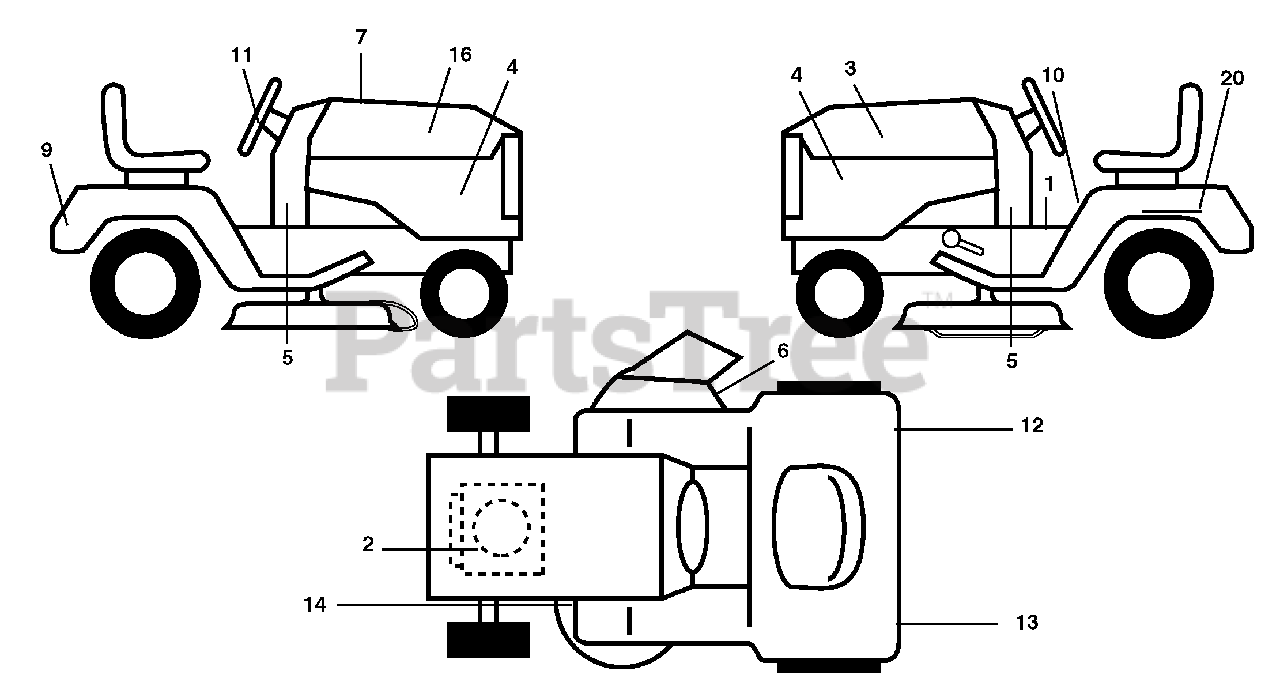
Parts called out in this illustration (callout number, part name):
2	Decalengine
3	Decal Hood LH
4	Decal Side Panel Logo
5	Decal Dash
6	Decal Warning, Keep Hand Away
7	Decal Replacement Parts
9	Decal Fender Logo
10	Decal Fender Danger E/F
11	Decal Ins Strg Whl
12	Decal Fend Reflector Rh
13	Decal Fend Reflector Lh
14	Decal V-Belt Schematic
16	Decal Hood Rh
20	Decal Bat Dan/Psn
20	Pad Footrest LH
20	Pad Footrest RH
20	Decal Handle Lft Height Adjust
20	Decal Chassis Disconnect
20	Manual Operator's E&F
20	Manual Parts
